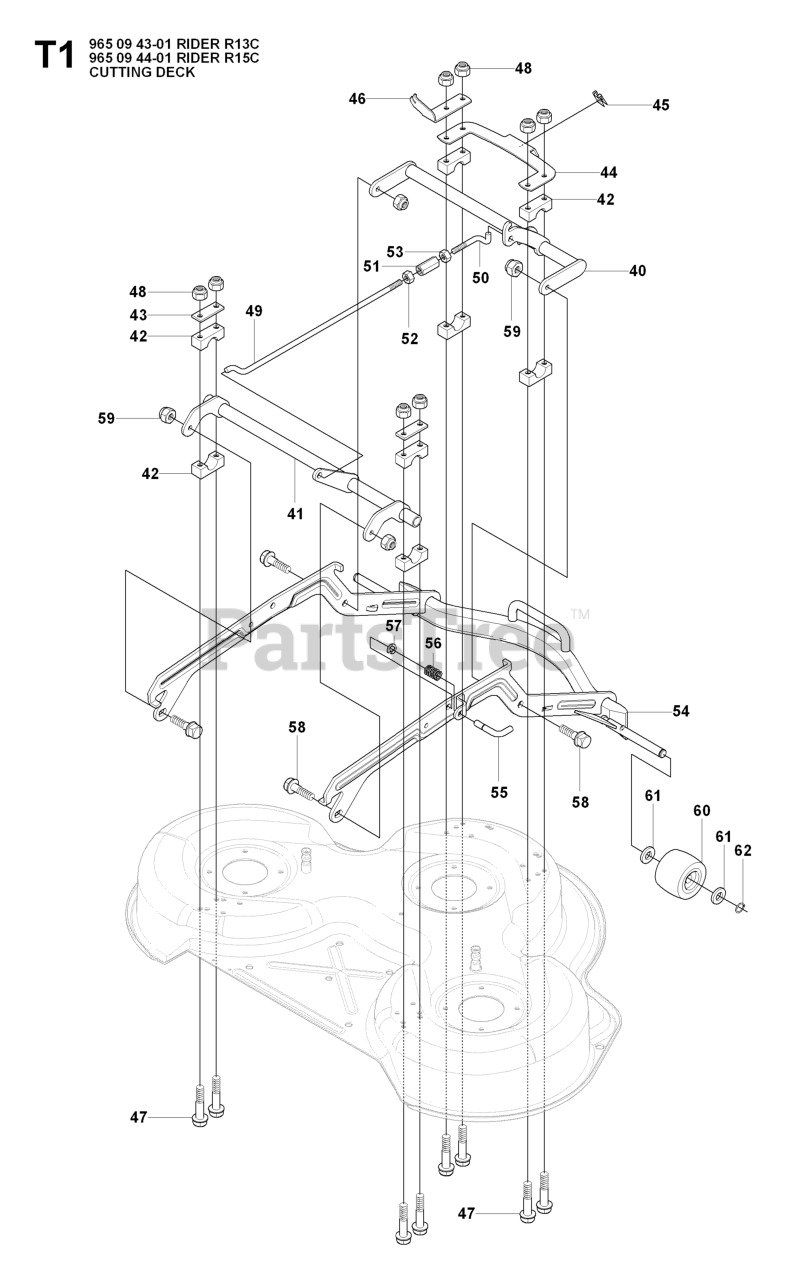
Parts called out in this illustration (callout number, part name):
46	BRACKET HANDLE
48	LOCKNUT M8
53	NUT
59	LOCKNUT M8
60	DECK ROLLER, FRONT
62	RETAINING RING SGA 15
